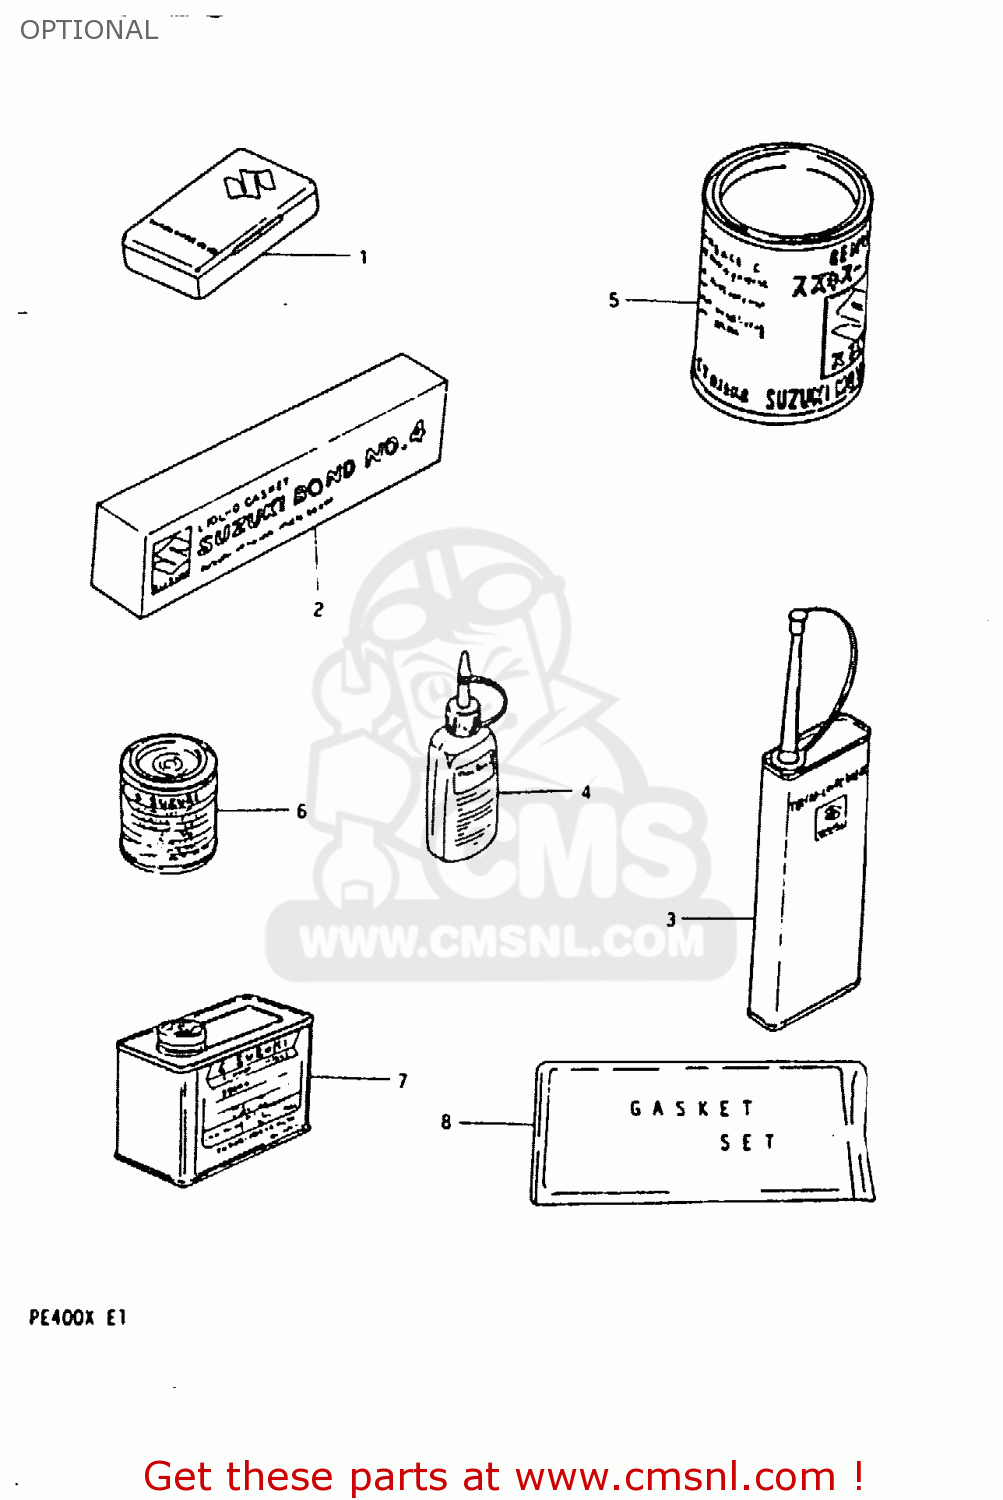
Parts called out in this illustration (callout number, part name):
1	TUBE REPARING TOOL
2	BOND 1104
3	THREAD LOCK NO.1401 CLEAR 200G
4	THREAD LOCK NO.1342
5	GREASE(C)EP2 LITHIUM 150G
6	PAINT,BLACK
7	PAINT (BLACK)
8	GASKET SET
